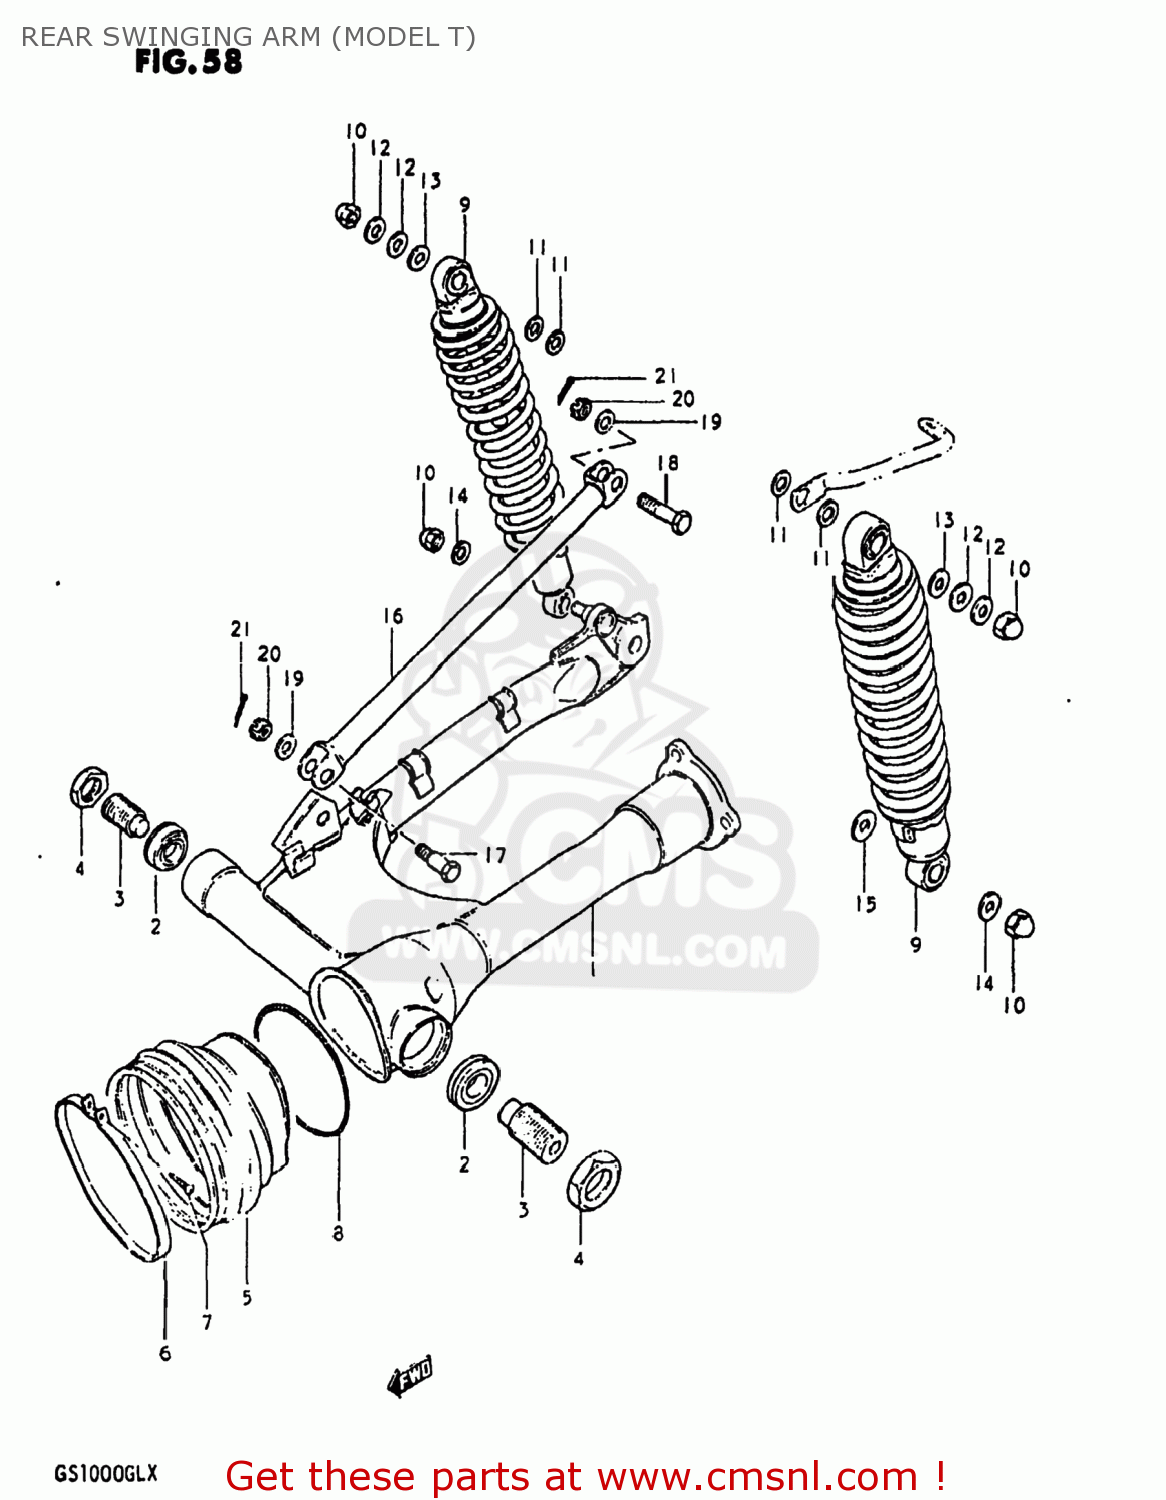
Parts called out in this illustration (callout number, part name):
1	SWING ARM ASSEMBLY,REAR
2	BEARING(17X40X13.25)
3	BOLT,REAR SWING ARM PIVOT
4	NUT
5	BOOT,PROPELLER SHAFT
6	CLAMP
7	SCREW 4X25
8	SPRING,PROPELLER SHAFT
9	ABSORBER ASSEMBLY,REAR SHOCK
10	NUT, LOWER LH
11	WASHER
12	WASHER
13	WASHER(10.5X24X3.2)
14	WASHER
15	WASHER
16	LINK,REAR TORQUE
17	BOLT
18	BOLT(10X39)
19	WASHER
20	NUT
21	PIN 20X20
